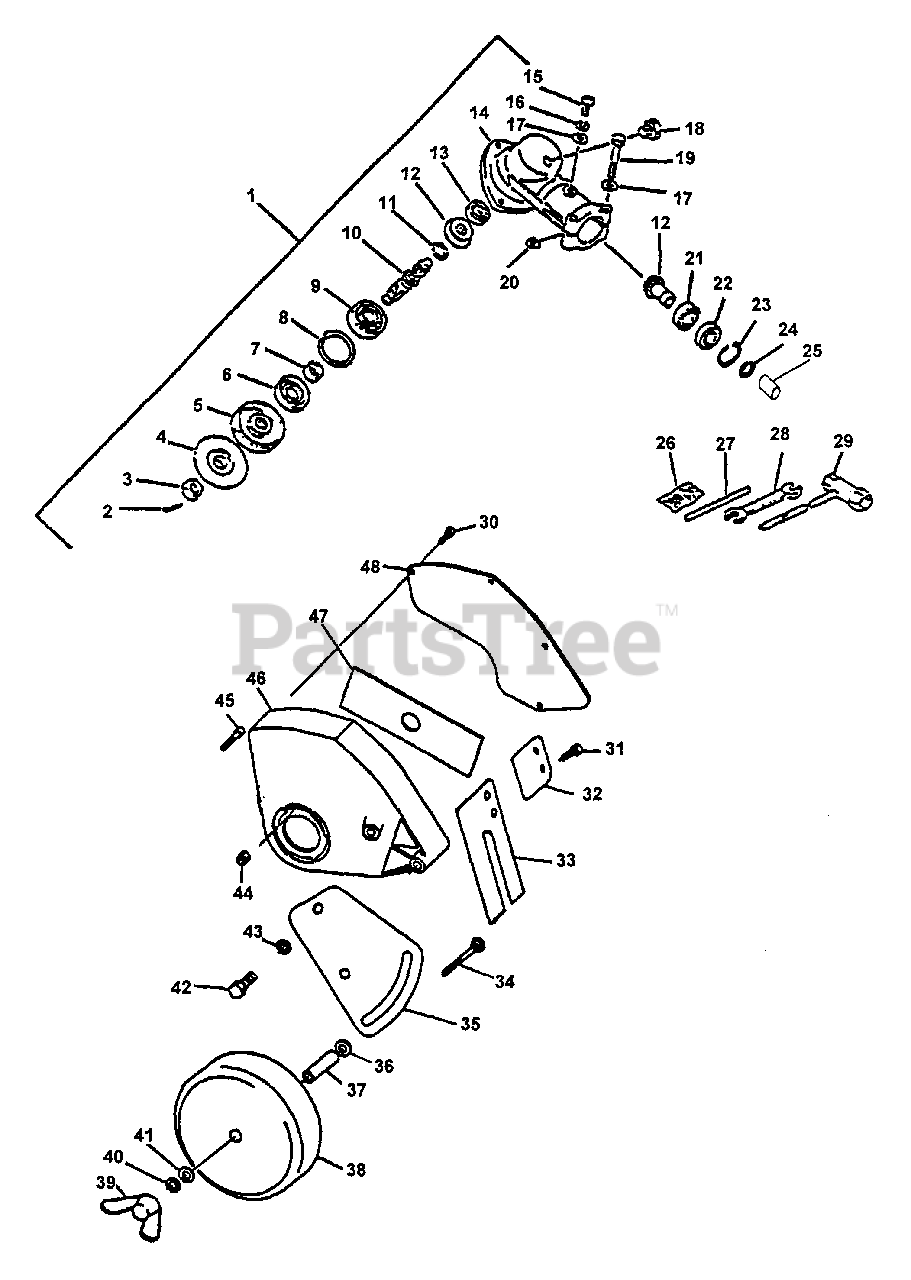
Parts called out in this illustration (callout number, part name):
1	GEAR CASE ASSY
2	PIN, SPLIT - 2X22
3	NUT - 10 -- LEFT HAND
4	ADAPTOR, BLADE - LOWER
5	ADAPTOR, BLADE - UPPER
6	SEAL, OIL
8	RING, RETAINING - 32
9	BEARING, BALL - 6201
10	GEAR - SHAFT
11	RING, RETAINING - 10
12	GEAR SET - BEVEL
13	BEARING, BALL - 609
14	CASE, GEAR
15	SCREW - 5X10
16	LOCKWASHER - 5
17	WASHER - 5
18	BOLT - 8X8
19	BOLT - 5X35
21	BEARING, BALL - 6900
22	BEARING, BALL - 6900Z
23	RING, RETAINING - 22
24	RING, RETAINING - 12
25	COLLAR
26	PIN, SPLIT - 2X22
27	LOCKING TOOL
28	SPANNER - 8X10mm
29	T-WRENCH - 17X19mm
30	SCREW - 4X12
31	SCREW - 4X14
32	FLAP, DEBRIS
33	FLAP, DEBRIS
34	BOLT - CARRIAGE
35	BRACKET, WHEEL
36	WASHER - 10
37	COLLAR - 12
38	WHEEL - 6X1.5
39	WINGNUT - 5/16-18
40	LOCKWASHER - 8
41	WASHER - 8
42	BOLT - 8X14
43	LOCKWASHER - 8
44	LOCKNUT - 5
45	SCREW - 5X22
46	NEW BLADE SHIELD
47	BLADE, EDGER
48	COVER, SHIELD
